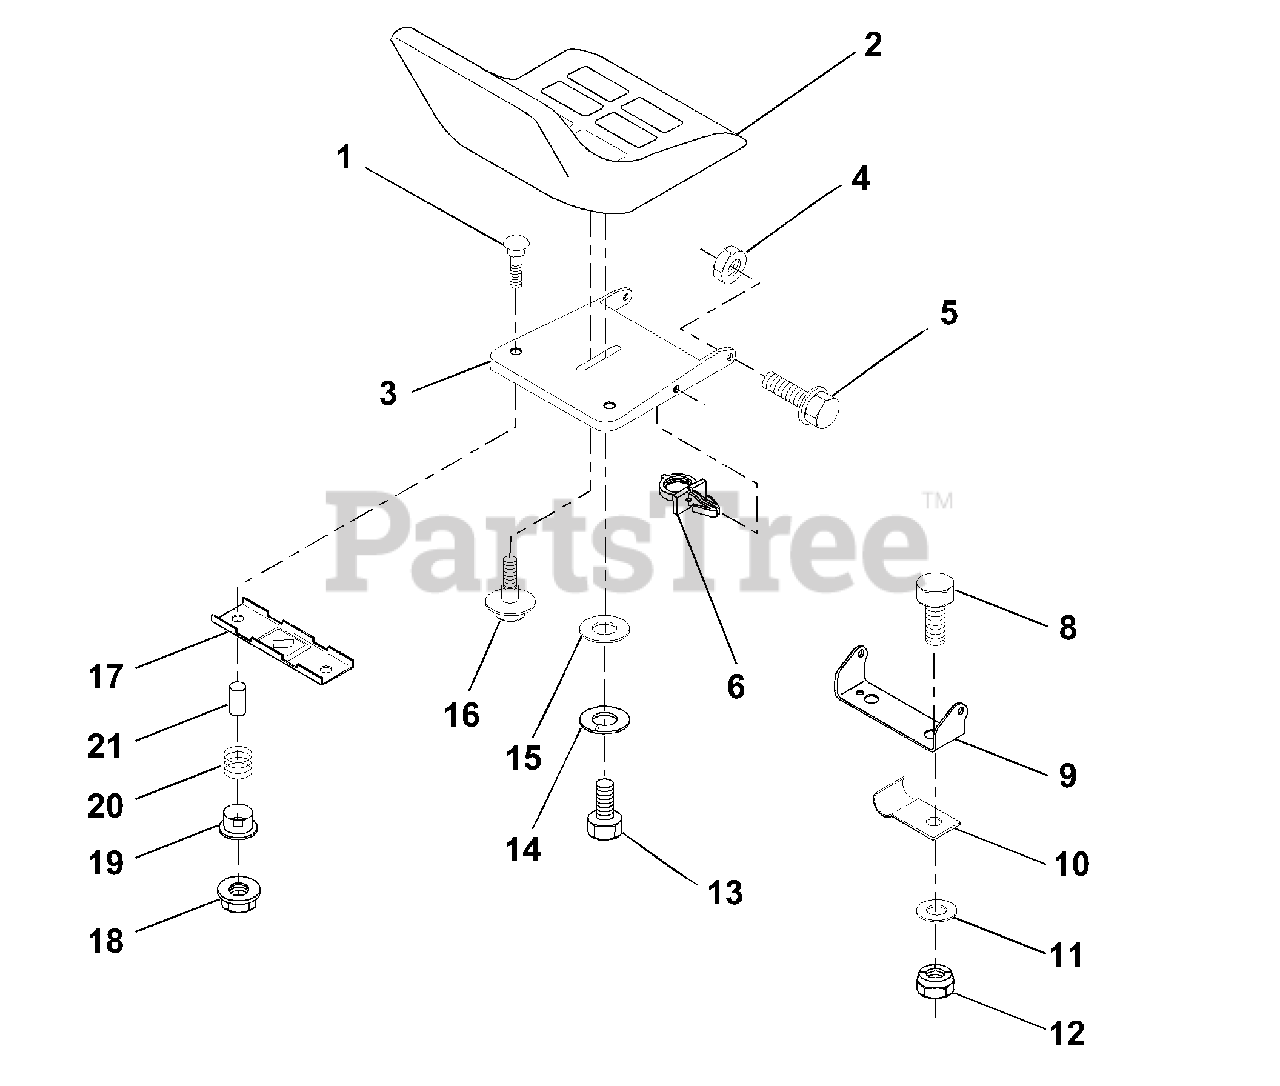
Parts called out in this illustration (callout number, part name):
1	Bolt, Carriage 1/4-20 x 1-3/8
2	Seat
3	Pan, Seat
4	Nut, Crownlock 5/16-18
5	Bolt, Shoulder 5/16-18 UNC
6	Clip, Push-In Hinged
8	Bolt, Fin Hex 3/8-16 UNC x 3/4
9	Bracket, Pivot Seat
10	Clip, Insulated
11	Washer 12/32 x 2 x 10 Ga.
12	Nut, Crownlock 3/8-16 UNC
13	Bolt Hex 1/2-13 x 7/8
14	Washer Lock Hvy. Hlicl Spring 1/2
15	Washer, 17/32 x 1-3/16 x 12 Ga.
16	Bolt, Shoulder
17	Bracket, Switch, Mounting
18	Nut, Hex Large Flange Lock
19	Bushing, Snap
20	Spring, Compression
21	Spacer, Split 28 Id. x .88 Lg.
